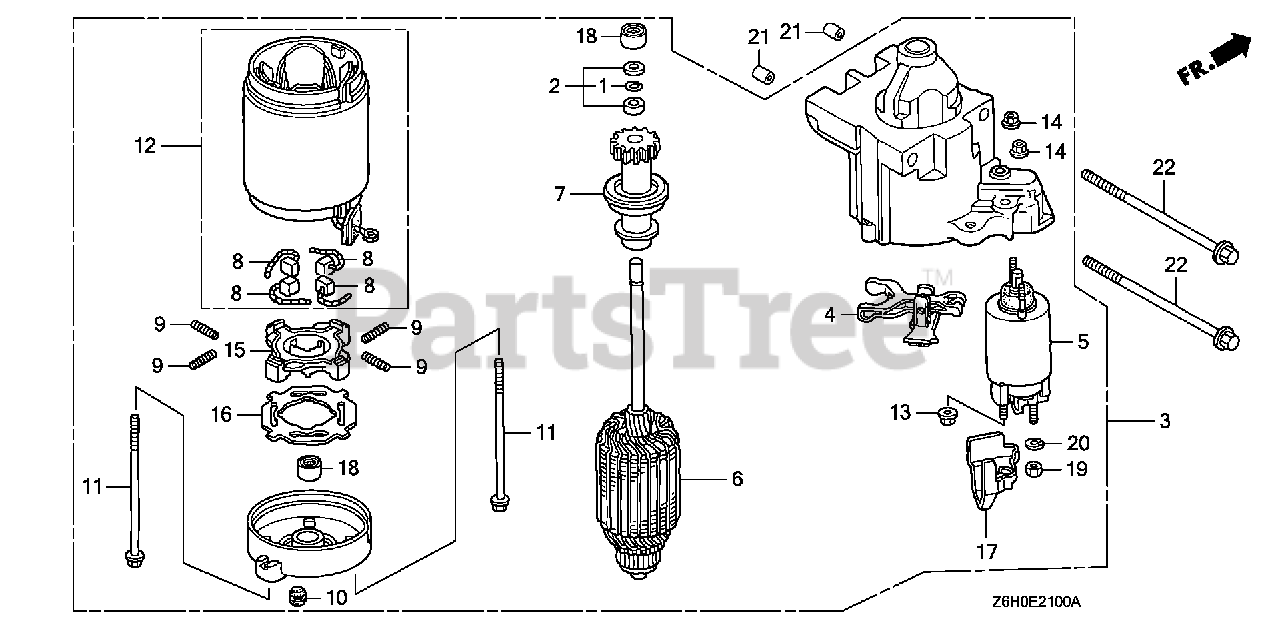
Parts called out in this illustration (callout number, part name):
1	RING, SNAP (DENSO)
2	COLLAR SET, CLUTCH STOP
3	STARTER MOTOR ASSY.
4	LEVER, PINION DRIVE
5	SWITCH ASSY., MAGNET
7	CLUTCH, OVERRUNNING
9	SPRING, BRUSH
11	BOLT, THROUGH
12	YOKE
13	NUT, HEX. (8MM)
15	HOLDER, BRUSH
16	INSULATOR, BRUSH HOLDER
17	COVER, TERMINAL
19	NUT, HEX. (8MM)
20	WASHER, SPRING (8MM)
21	PIN, DOWEL (10X12)
22	BOLT, FLANGE (8X110)
